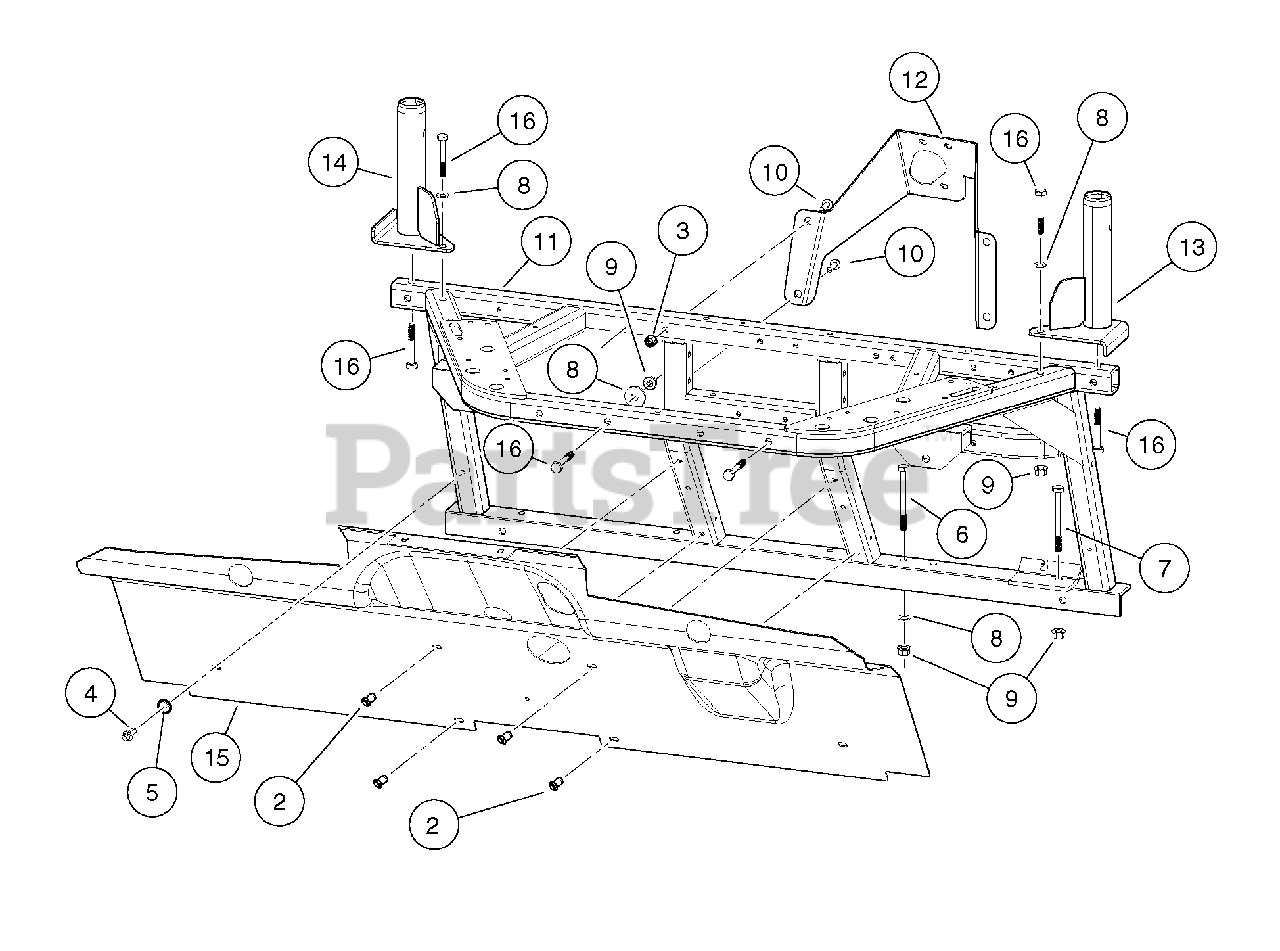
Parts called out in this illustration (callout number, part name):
1	Instl, Cowl Weldmnt/Splash Guard
2	Blind Rivet, Push Type
3	Nut,m8,all Metal Lock
4	M8-1.25x20 Taptite
5	Washer, Flat, 3/8, Blk Fin
6	Bolt, M10x1.50x100 (Black)
7	Bolt, M10 X 1.50 X 110 Black
8	Washer Hard,m10
9	Nut Flg M10 X 1.5 Mech Def
10	Bolt Flanged Head, M8 X 1.25 X 65
11	Weldment, Dash, Front
12	Bracket, Column, Steering
13	Weldment, Front, Base, ROPS, Right-Hand
14	Weldment, Front, Base, ROPS, Left-Hand
15	Guard, Splash, Gas Injection
16	Bolt, M10 X 1.50 X 65
